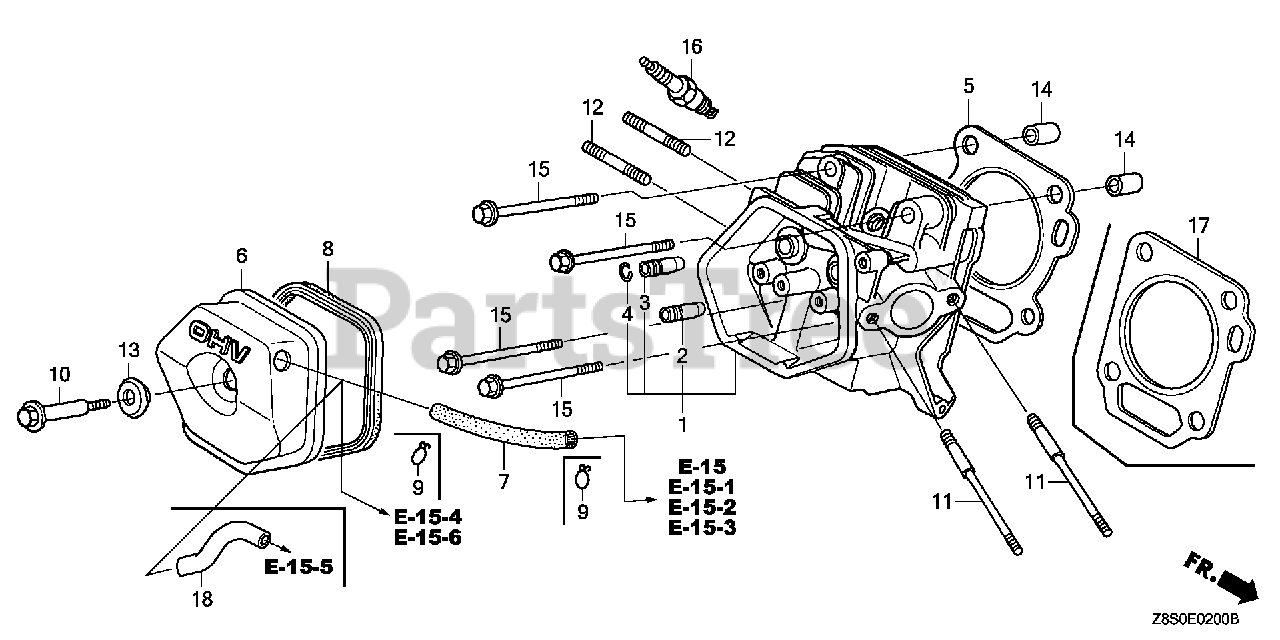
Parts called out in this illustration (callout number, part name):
1	CYLINDER HEAD
2	GUIDE, VALVE (OS)
3	GUIDE, EX. VALVE (OS)
4	CLIP, VALVE GUIDE
6	COVER, HEAD
6	COVER, CYLINDER HEAD
8	GASKET, CYLINDER HEAD COVER
10	BOLT, HEAD COVER
11	BOLT, STUD (8X123)
12	BOLT 2, STUD (8X32)
13	WASHER, HEAD COVER
14	PIN A, DOWEL (12X20)
15	BOLT, FLANGE (10X80)
16	SPARK PLUG (BPR5ES) (NGK)
16	SPARK PLUG (W16EPR-U) (DENSO)
16	SPARK PLUG (BPR6ES) (NGK)
16	SPARK PLUG (W20EPR-U) (DENSO)
17	GASKET, CYLINDER HEAD
18	TUBE, BREATHER
